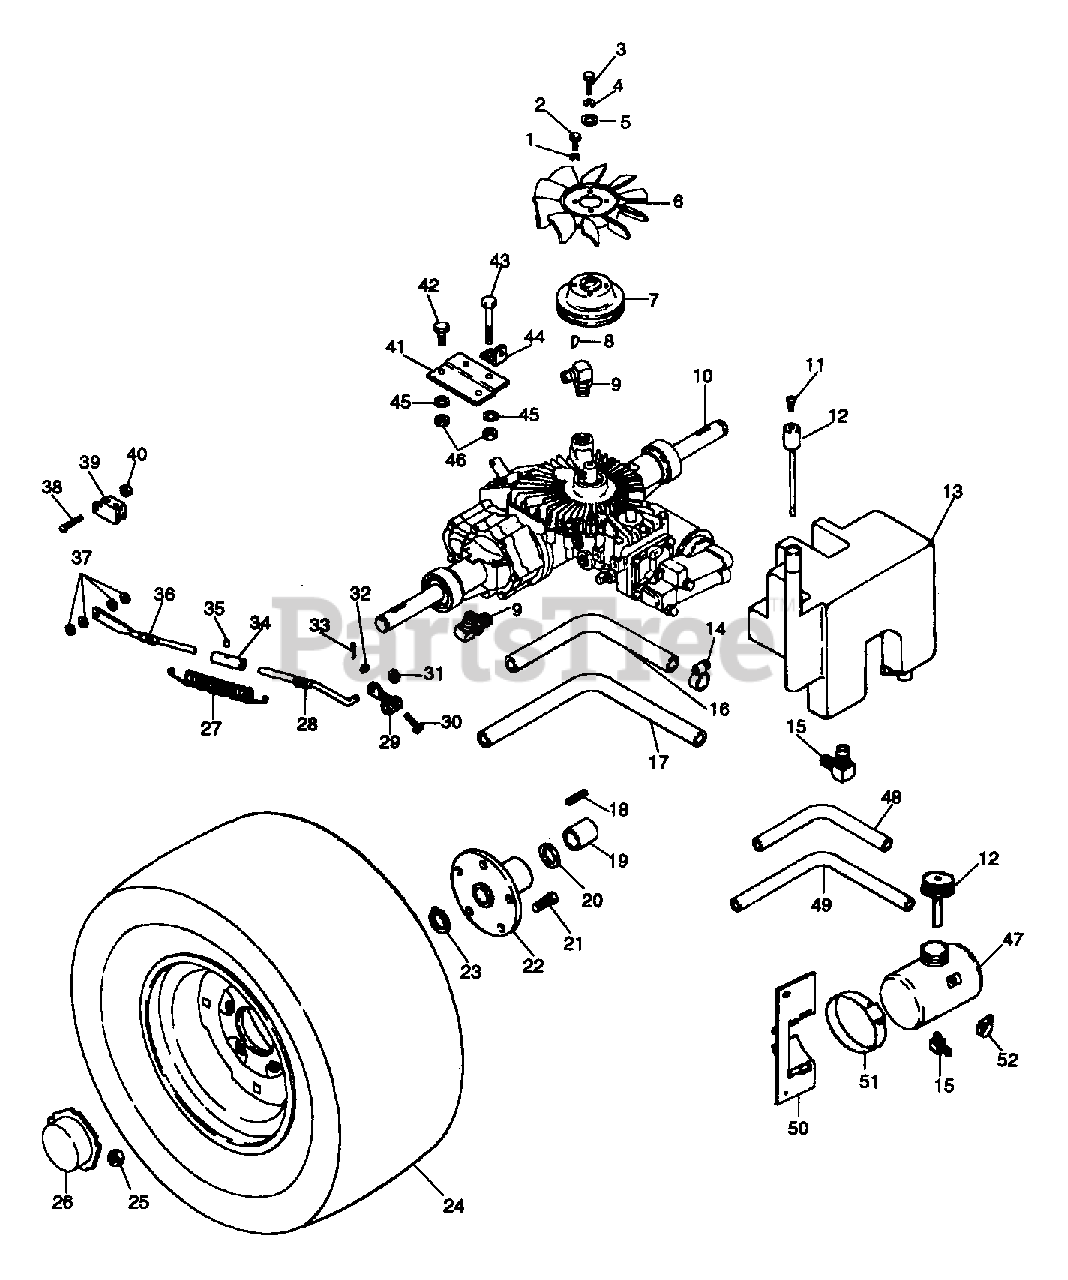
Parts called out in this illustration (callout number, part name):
1	WSHR-LK-EXT #10 ID X .022
2	BLT-HEX 10-24X.38 PL GR2
3	BLT-HEX .25-20X1.00 PL GR5
4	WSHR-LK .250X.077 HVY PL
5	WSHR-FL-STL .265X1.370X.145
7	SHEAVE - TRANSAXLE
7	TRANSAXLE SHEAVE
8	KEY-WDRF .188X.625X.25 SAE 61
9	FITTING
10	TRANSAXLE
10	TRANSAXLE - HYDRO
10	TRANSAXLE HT14S
11	SCR-VENT SL 8-32X.250
12	DIP STICK
12	CAP W/DIPSTICK
13	OIL RESERVOIR
14	CLAMP-HOSE WRM .38/.62X.50 #10
15	HOSE FITTING
15	FITTING-90 DEGREES
16	HOSE
17	HOSE
18	KEY-STR .25X2.0X.25
19	SPACER 1.006X1.437X1.928
20	WSHR-FL-STL 1.010X1.505X.062PL
21	BLT-LUG SERNKHDND .44-20X1.188
22	WHEEL HUB
23	RG-RTNG-EXT 1.00X.078
24	WHL
24	T/WHL ASSY 10.50X23
24	TIRE
24	WHL 12X8.50
24	T/WHL ASSY
25	NUT-LUG .437-20 YWZC
26	REAR HUB CAP
27	SG-TENS .090X.96X4.0 WLD 23
29	ARM-DUMP VALVE
30	BLT-HEX .25-20X1.00 GR2
31	WSHR-FL-STL.344X.688X.065PL
32	NUT-LK-CTR .250-20 PL
33	PIN-COTR .09X.75 PL
34	COLLAR .380X.625X2.00
35	PIN-ROLL .125X.63
37	WSHR-FL-STL.281X.62X.065 PL
38	SCR-MCH 10-24X.88 SLRH PL
40	NUT-LK TOP 10-24 PL
41	BRACKET
42	BLT-HEX .38-16X1.00 PL GR5
43	BLT-HEX .38-16X3.25 PL GR5
44	SPRING ANCHOR
45	WSHR-FL-STL .390X.750X.125 PL
46	NUT-LK TOP .375-16 GR C YWZC
47	EXPANSION TANK
48	HOSE 40 1/2
49	HOSE 45
50	TANK BRACKET
51	HOSE CLAMP- 3"-3.25"
52	HOSE CLAMP
